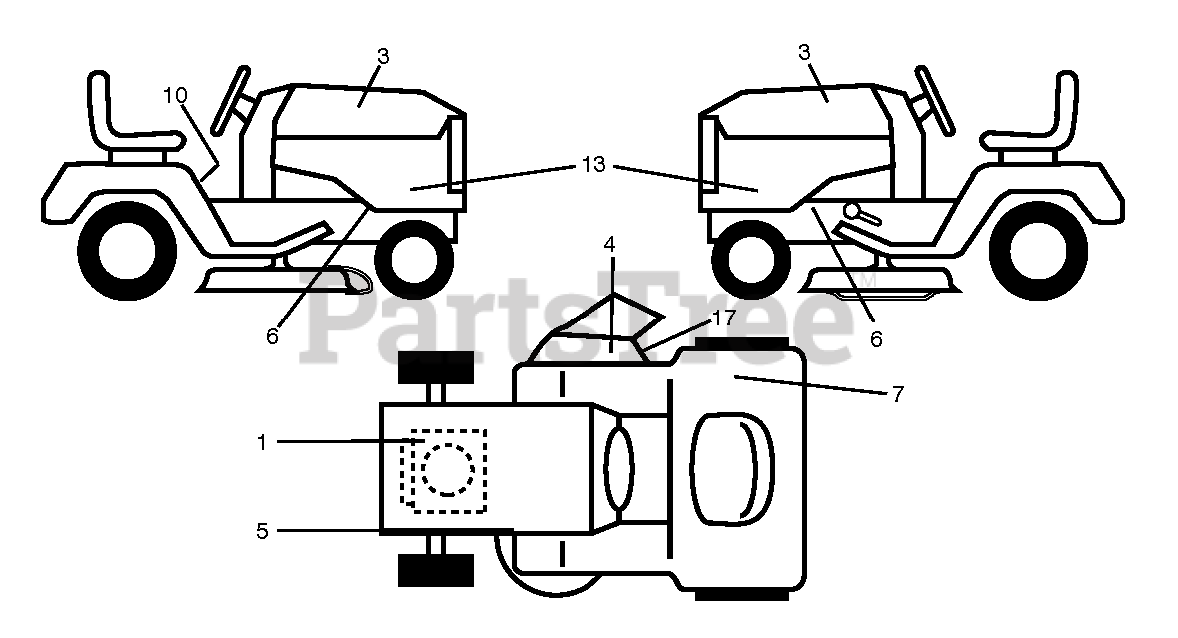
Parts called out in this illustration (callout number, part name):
1	DECAL.ENGINE.WARNING
3	DECAL.WB.178MM.15.HUSQ.NEWBRAN
4	DECAL, DECK DEFLECTOR, WARNING
5	DECAL.V-BELT.SCH.42/46"MEC/ELE
6	DECAL.CHASSIS.HOT.MUFFLER
7	DECAL.CONSUMPT.MEXICO.3.26L/H
10	DECAL.TRACTOR.SADDLE
13	DECAL.SDPNL.LTH1842.KOH.HUSQ
17	DECAL.DFLCTR.WARNNG.CTFNGR.SYM
